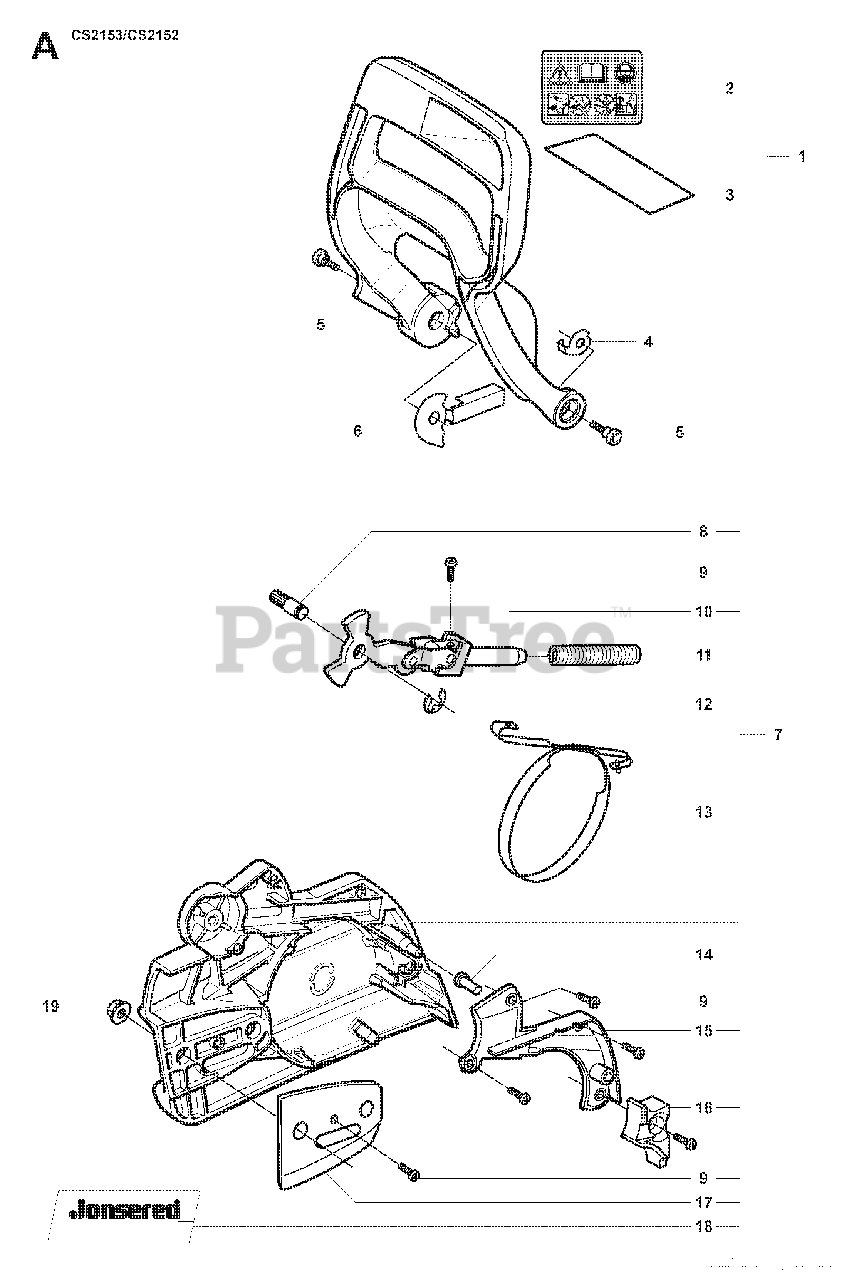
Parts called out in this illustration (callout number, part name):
1	HAND GUARD
3	PROTECTOR
5	SCREW
6	PROTECTOR
7	CHAIN BRAKE
13	BRAKE BAND
16	PROTECTOR
19	NUT M8 FLANGE
